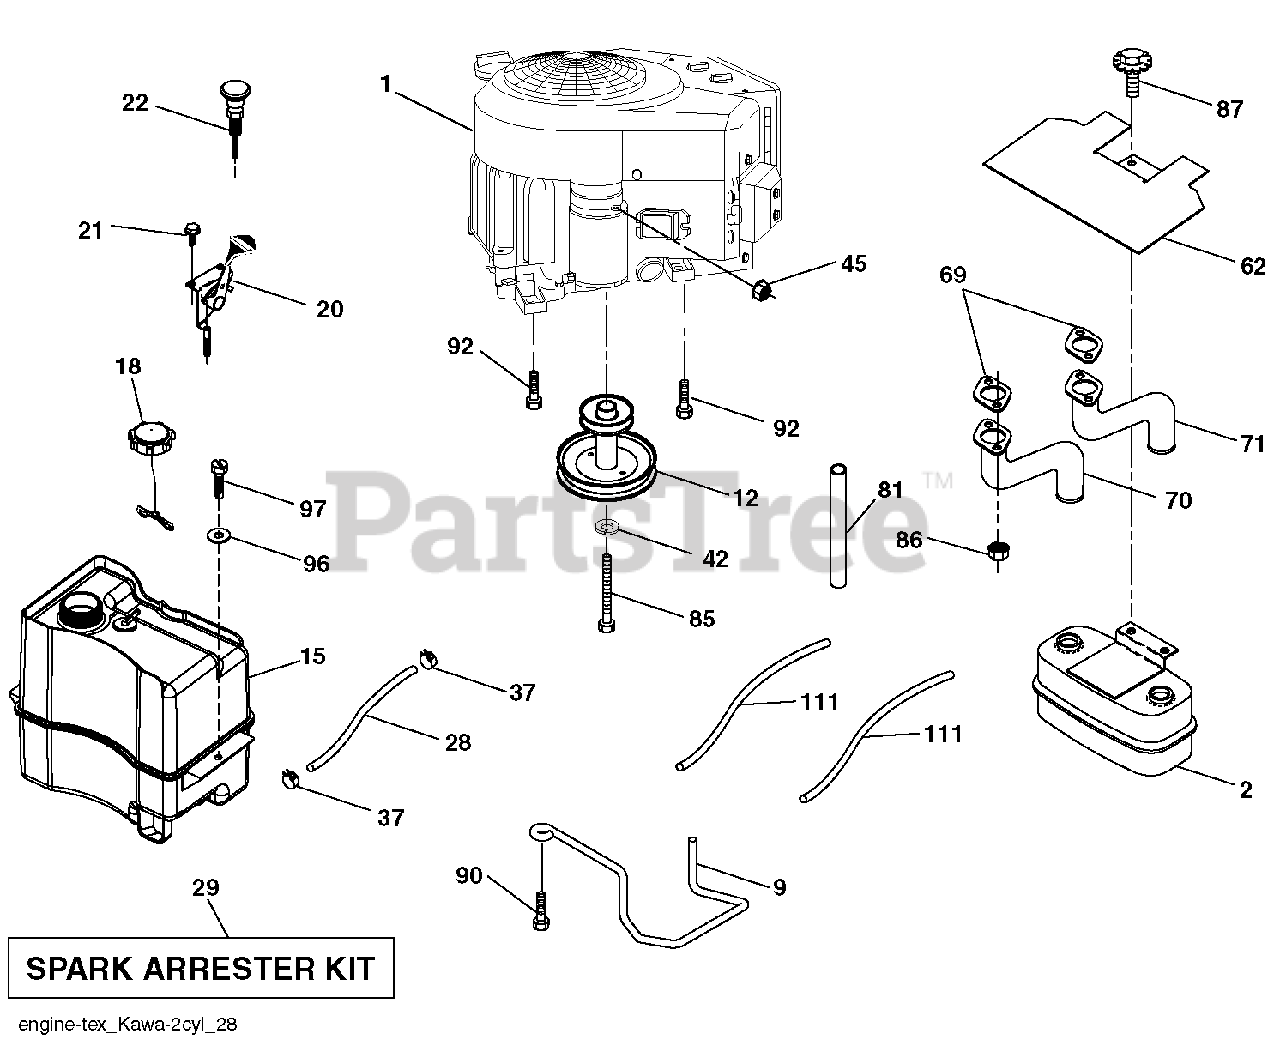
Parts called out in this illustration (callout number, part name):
2	MUFFLER.ASM.TWN.EXTNDED.DFLCTR
9	KEEPER BELT ENGINE
12	PULLEY ENGINE
15	TANK.ASM.FRT.2.5 GAL.W/CAP.EPA
18	CAP.2.25'.VENTED.TETHER .EPA
20	CONTROL.THROTTLE.COBRA.BLACK
21	SCREW.#10 X 0.750.BOS
22	CONTROL, CHOKE
28	LINE.FUEL.20"FRONT.EMI
29	KIT.SPARK ARRESTOR 794945 B&S
37	HOSE CLAMP
42	LOCKWASHER
45	NUT
62	SHIELD.HEAT.MUFFLER
69	GASKET.EXHAUST.KOHLER
70	TUBE.EXHAUST.RH.FR961/FR730
71	TUBE.EXHAUST.LH.FR961/FR730
81	TUBE, DRAIN OIL ASM.
85	BOLT HEX 7/16-20X4-1/4"
86	BLADE ADAPTER
87	Bolt, 5/16-18 X 1-3/4
90	SCREW 3/8-16X1
92	SCREW 3/8-16X1
97	SCREW HEXWSHR 1/4-20X3/4
111	RP PURGE LINE
